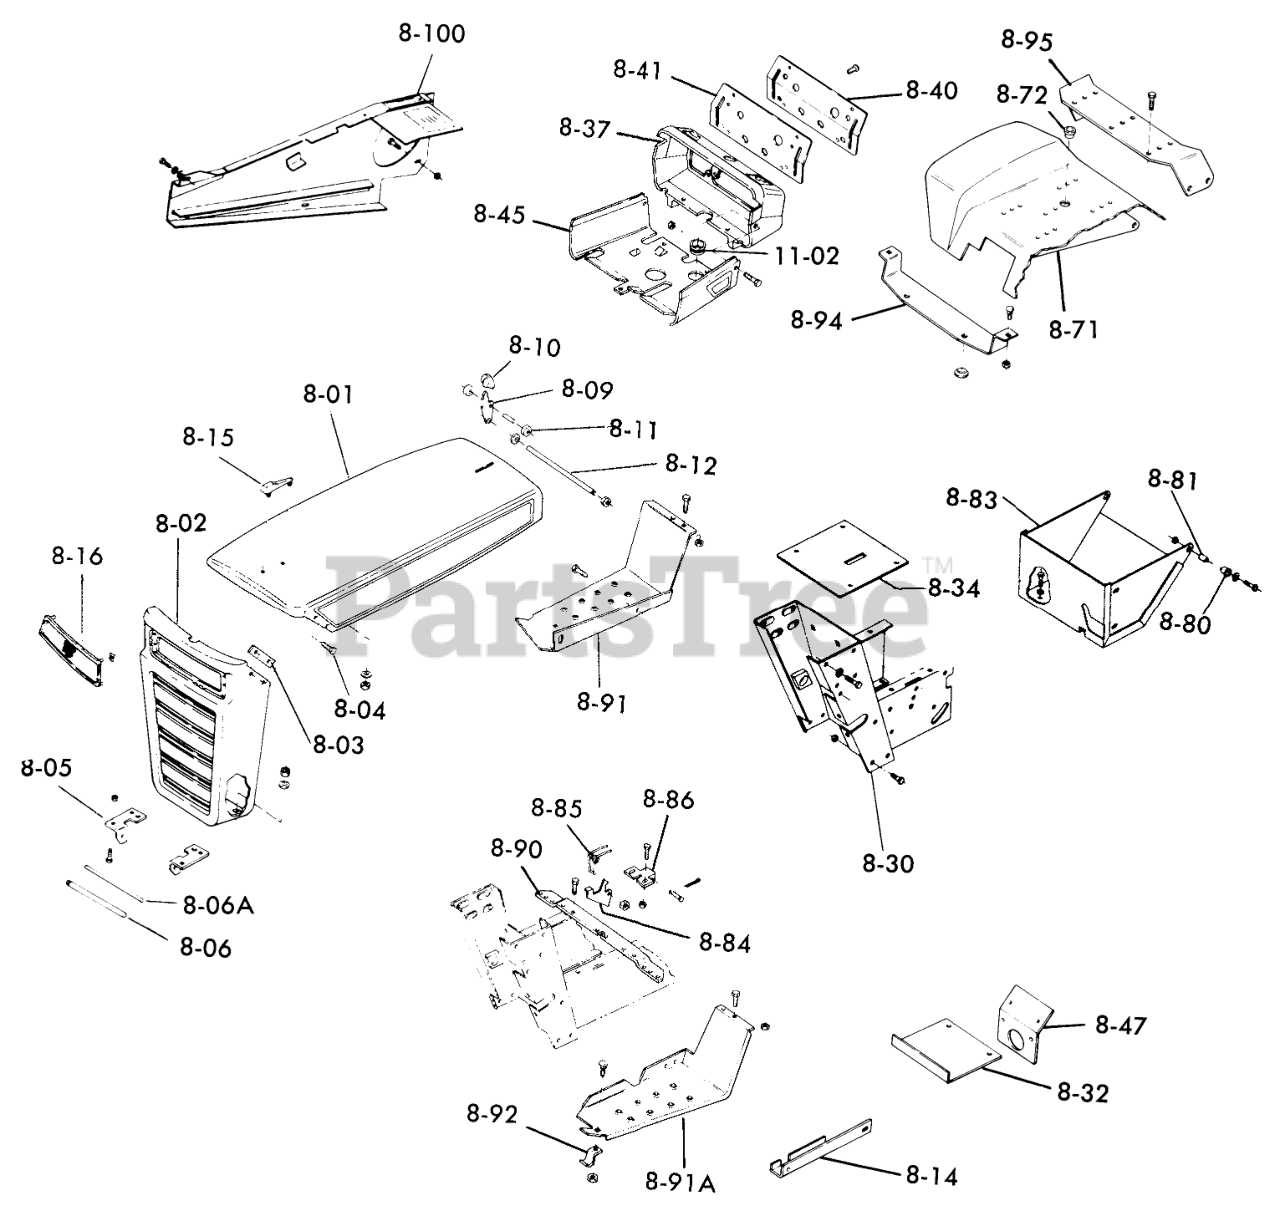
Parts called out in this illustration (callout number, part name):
8-01	Hood Assembly
8-02	Spacer Sleeve
8-03	Plate, Grille
8-06	GRILL PIVOT ROD
8-06A	ROD-HOOD STOP
8-09	LEVER HOOD LATCH
8-10	KNOB
8-15	Hood Ornament
8-16	ESCUTCHEON PLATE
8-32	Cover-Dust
8-80	BUSHING-FLANGED
8-85	Spring
8-92	BRACKET
